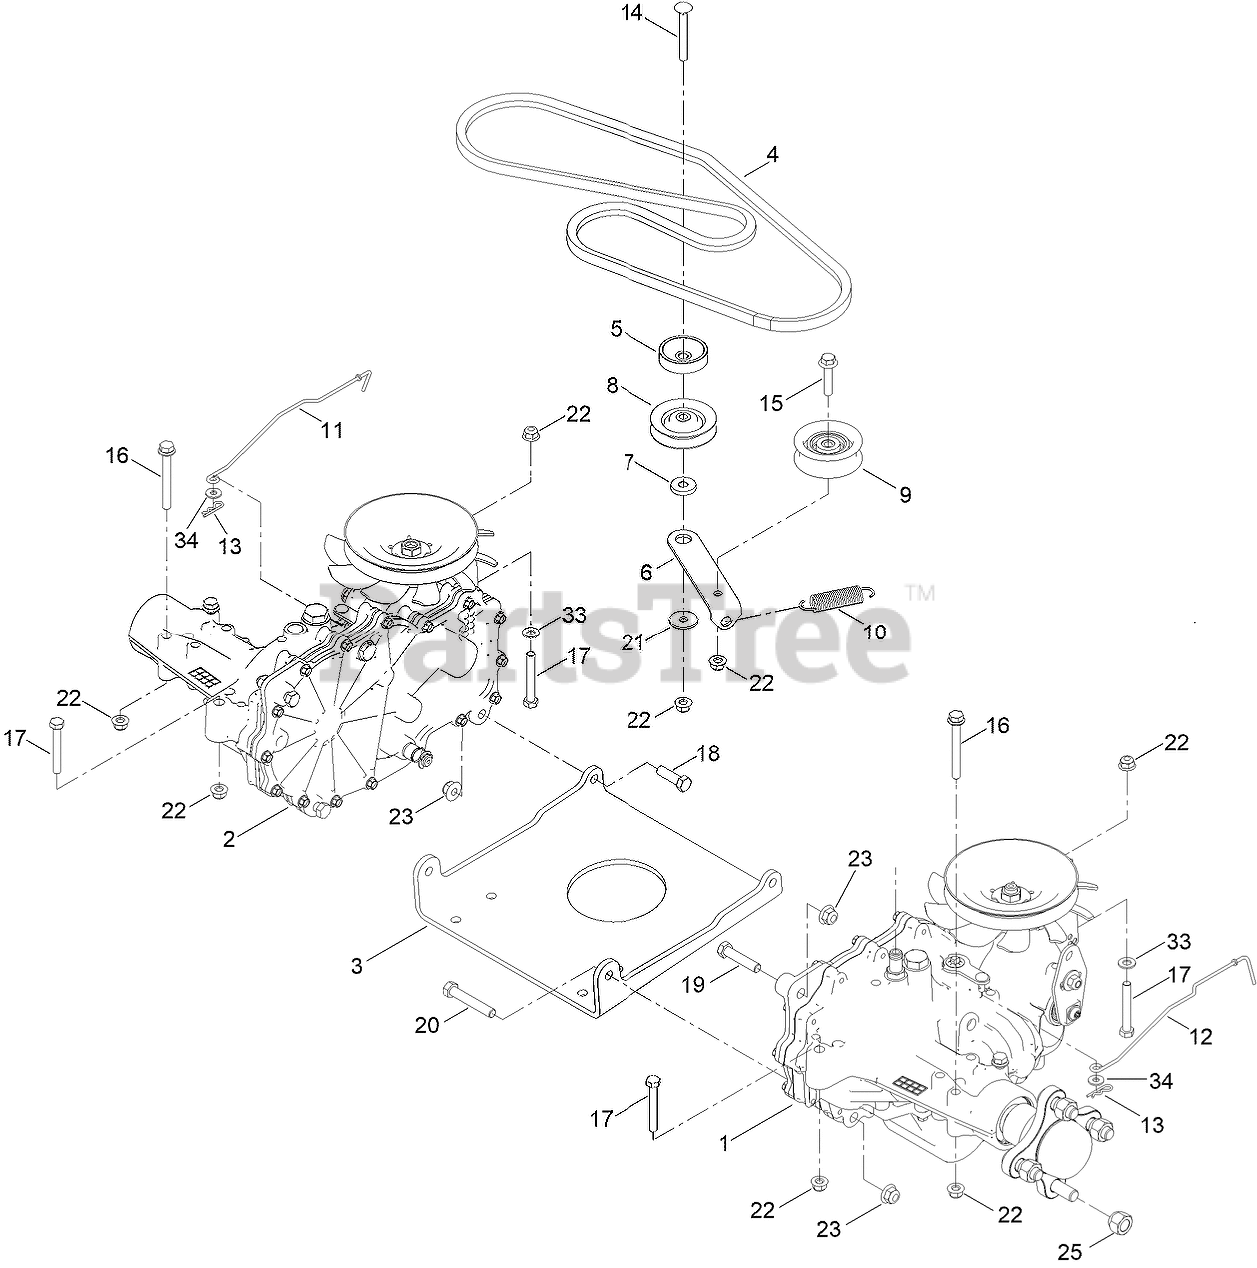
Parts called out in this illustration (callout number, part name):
1	LH HYDRO TRANSMISSION ASM
2	RH HYDRO TRANSMISSION ASM
3	PLATE- HYDRO
4	V-BELT
5	SPACER
6	ARM-IDLER
7	SPACER-IDLER ARM
9	PULLEY-IDLER, FLAT
10	SPRING-PEDAL, RETURN
11	ROD-BYPASS, RH
12	ROD-BYPASS, LH
14	SCREW-CARR
15	SCREW-HHF
16	SCREW-HHF
17	SCREW-HH
18	SCREW-HH
19	SCREW-HH
20	SCREW-HH
21	WASHER-PIVOT
22	NUT-HF, NI
23	NUT-HF, NI
25	NUT-LUG
33	WASHER-PLAIN
34	WASHER
